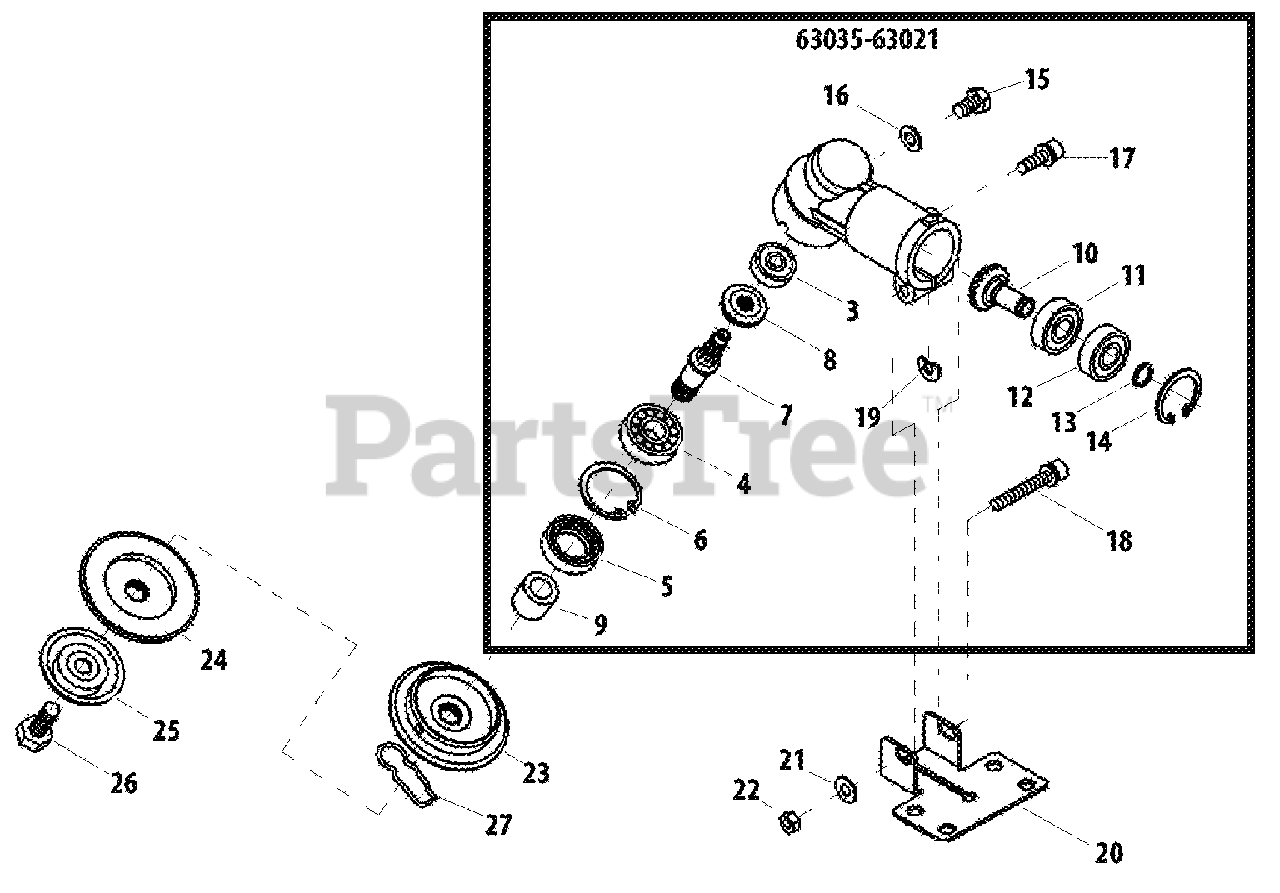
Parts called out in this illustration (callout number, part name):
3	BEARING, BALL - 609
4	BEARING, BALL - 6201
5	SEAL, OIL
6	RING, RETAINING - 32
7	GEAR - SHAFT
8	GEAR - BEVEL
9	COLLAR
10	PINION SET
11	BEARING, BALL - 6901
12	BEARING, BALL - 6901ZZ
13	RING, RETAINING
14	RING, RETAINING - 24
15	BOLT - 6X10
16	WASHER
17	SCREW - 5X16
18	SCREW - 6X40
19	SHIM
20	BRACKET
21	WASHER - 6
22	NUT - 6
23	HOLDER - A
24	ADAPTOR, BLADE - UPPER
25	GUARD
26	BOLT - 8 -- LEFT HAND
27	CLIP
6303563021	GEAR CASE ASSY
